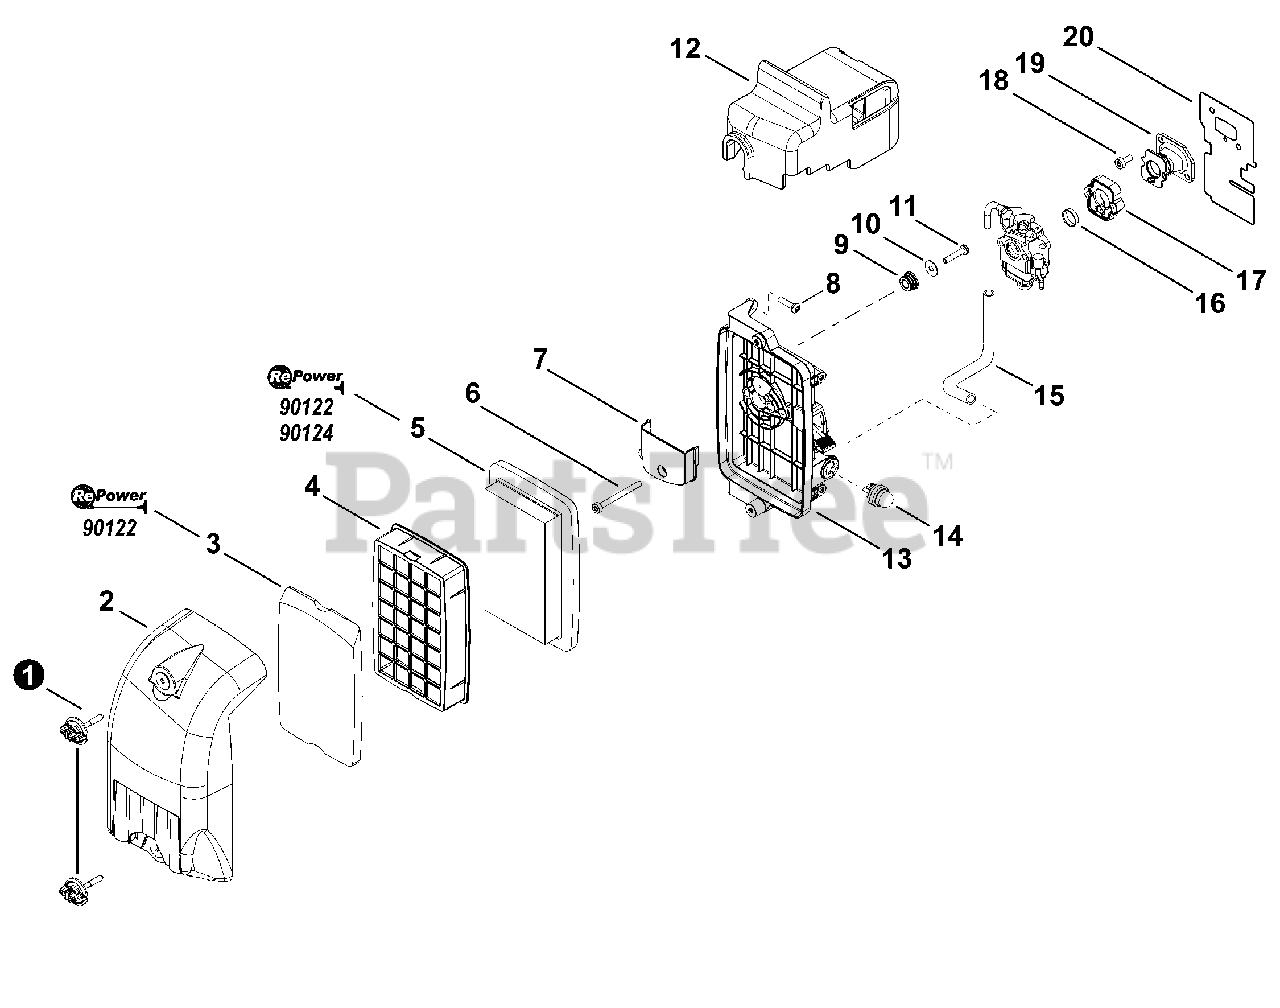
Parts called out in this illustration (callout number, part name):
1	KNOB, COVER
2	COVER, AIR FILTER
3	PRE-FILTER -- FOAM
4	RETAINER, PRE-FILTER
5	FILTER, AIR
6	SCREW - 5×55
7	PLATE, PREVENT
8	SCREW - 5×20
9	GUIDE, CABLE
11	SCREW - 5×16
12	CAP, CARBURETOR
13	AIR FILTER CASE ASSY
14	PUMP, PURGE
15	PIPE - 3×5×140 -- BLACK
16	SEAL, INTAKE
17	ADAPTOR, INTAKE
18	SCREW - 5×12
19	BELLOWS
20	GASKET, INTAKE
